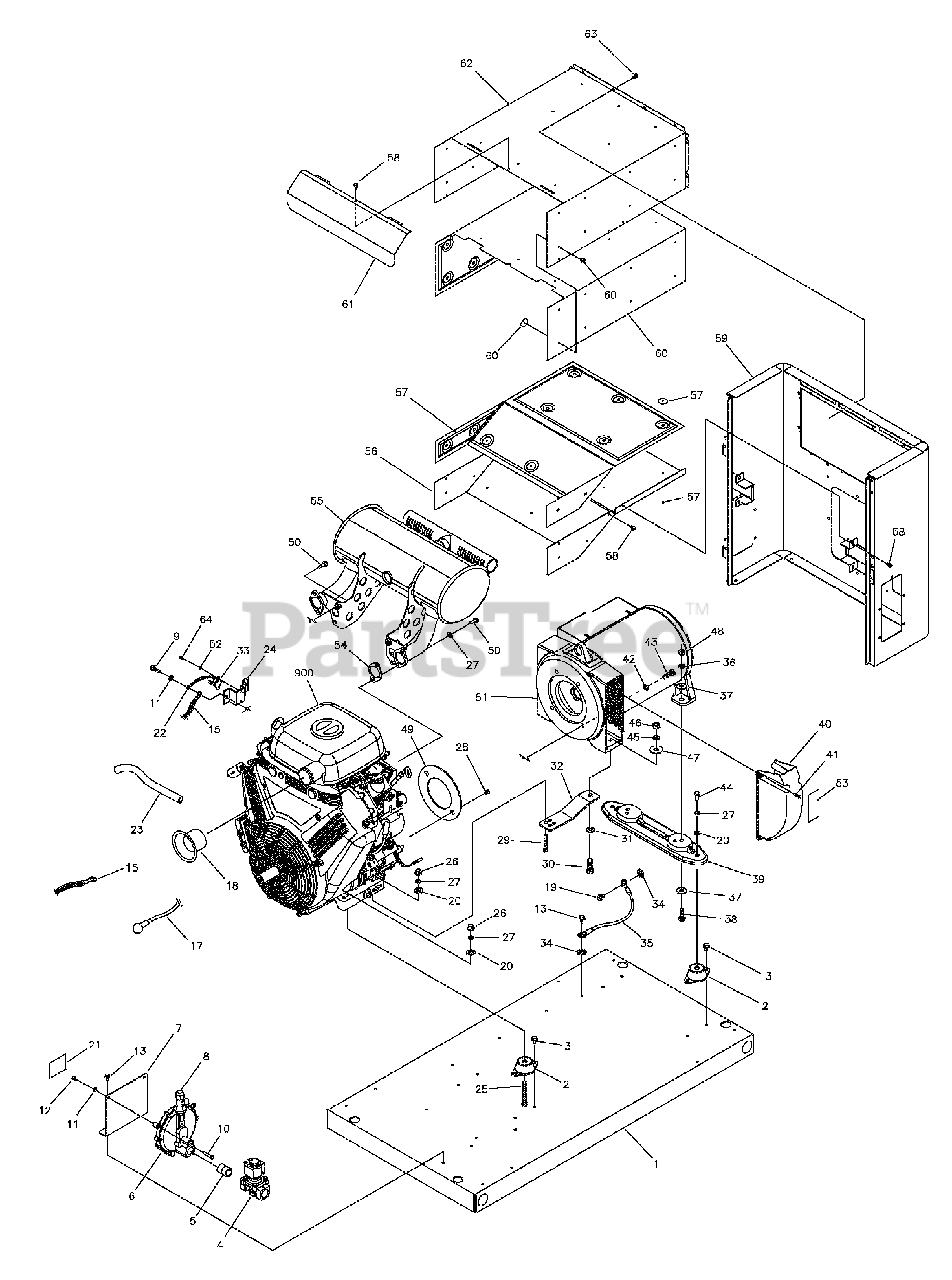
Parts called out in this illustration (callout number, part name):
1	BASE
2	MOUNT, Vibration
4	SOLENOID, Gas Fuel
6	REGULATOR, NG/LPG
7	BRACKET
9	* CAPSCREW, Hex Head, M6-1.0 x 16
10	* CAPSCREW, Hex Head, M6-1.0 x 30
11	* WASHER, Lock, 1/4
12	* NUT, M6-1.0
13	BOLT
19	* CAPSCREW, Hex Head, M6-1.0 x 12
20	* WASHER, Flat, 5/16-M8
23	HOSE, Oil Drain
24	PLATE, Temp Switch
25	* CAPSCREW, Hex Head, 5/16-18 x 2-1/2
26	* NUT, 5/16-18
27	* WASHER, Lock, 5/16-M8
28	* CAPSCREW, Hex Head, 5/16-24 x 3/4
29	* CAPSCREW, Hex Head, 5/16-18 x 2
30	* CAPSCREW, Hex Head, M12-1.75 x 35
31	* WASHER, M12
32	SUPPORT, Engine
33	SWITCH, Temp
34	* WASHER, Shakeproof, M6-1/4
36	* WASHER, Lock, M10
37	* WASHER, Flat, M10
38	* CAPSCREW, Hex Head, M10-1.5 x 30
39	SUPPORT, Alternator
41	* SCREW, Phillips Head, M5-0.8 x 20
42	* WASHER, Lock, 3/8
43	* CAPSCREW, 3/8-16 x 1-1/4
44	* CAPSCREW, Hex Head, 5/16-18 x 3/4
45	* WASHER, Lock, M12
46	* NUT, Hex, M12
47	* WASHER, Flat, M12
48	* NUT, M10
50	SCREW
51	ALTERNATOR
52	* WASHER, Lock, #4
59	BULKHEAD, Alternator
62	BOX, Muffler, Top
64	* SCREW, Phillips Head, 4-40 x 0.19
900	** ENGINE
